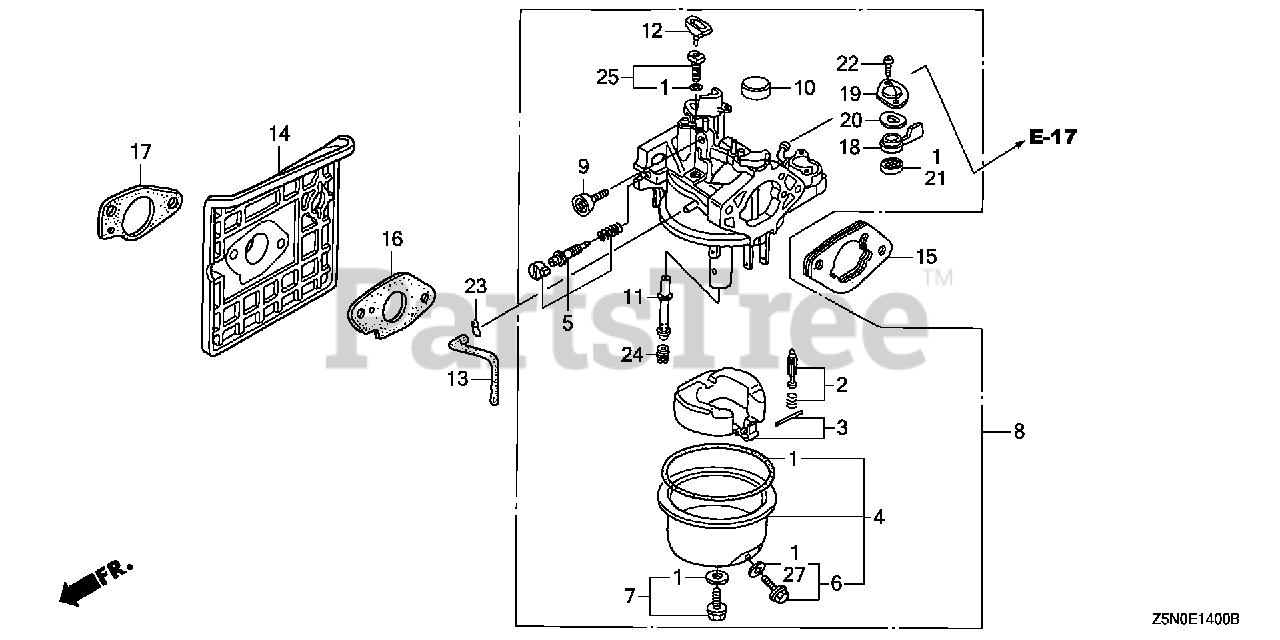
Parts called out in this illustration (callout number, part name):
1	GASKET SET (EXCEPT 16173-001-004)
2	VALVE SET, FLOAT
4	CHAMBER SET, FLOAT
5	SCREW SET, PILOT
6	SCREW SET, DRAIN
7	SCREW SET
8	CARBURETOR ASSY. (BE81H B)
8	CARBURETOR ASSY. (BE81M A)
9	SCREW, THROTTLE STOP
10	CAP, CHOKE DUST
11	NOZZLE, MAIN
12	COLLAR, SETTING
13	TUBE, AIR VENT (75MM)
14	INSULATOR, CARBURETOR
15	SPACER, CARBURETOR
16	GASKET, CARBURETOR
17	GASKET, INSULATOR
18	LEVER, PETCOCK
19	PLATE, LEVER SETTING
20	SPRING, PETCOCK LEVER
21	GASKET, PETCOCK
22	SCREW, PAN (3X6)
23	CLIP, TUBE (B8)
24	JET, MAIN (#88)
24	JET, MAIN (#90)
24	JET, MAIN (#92)
25	JET SET, PILOT (#38)
